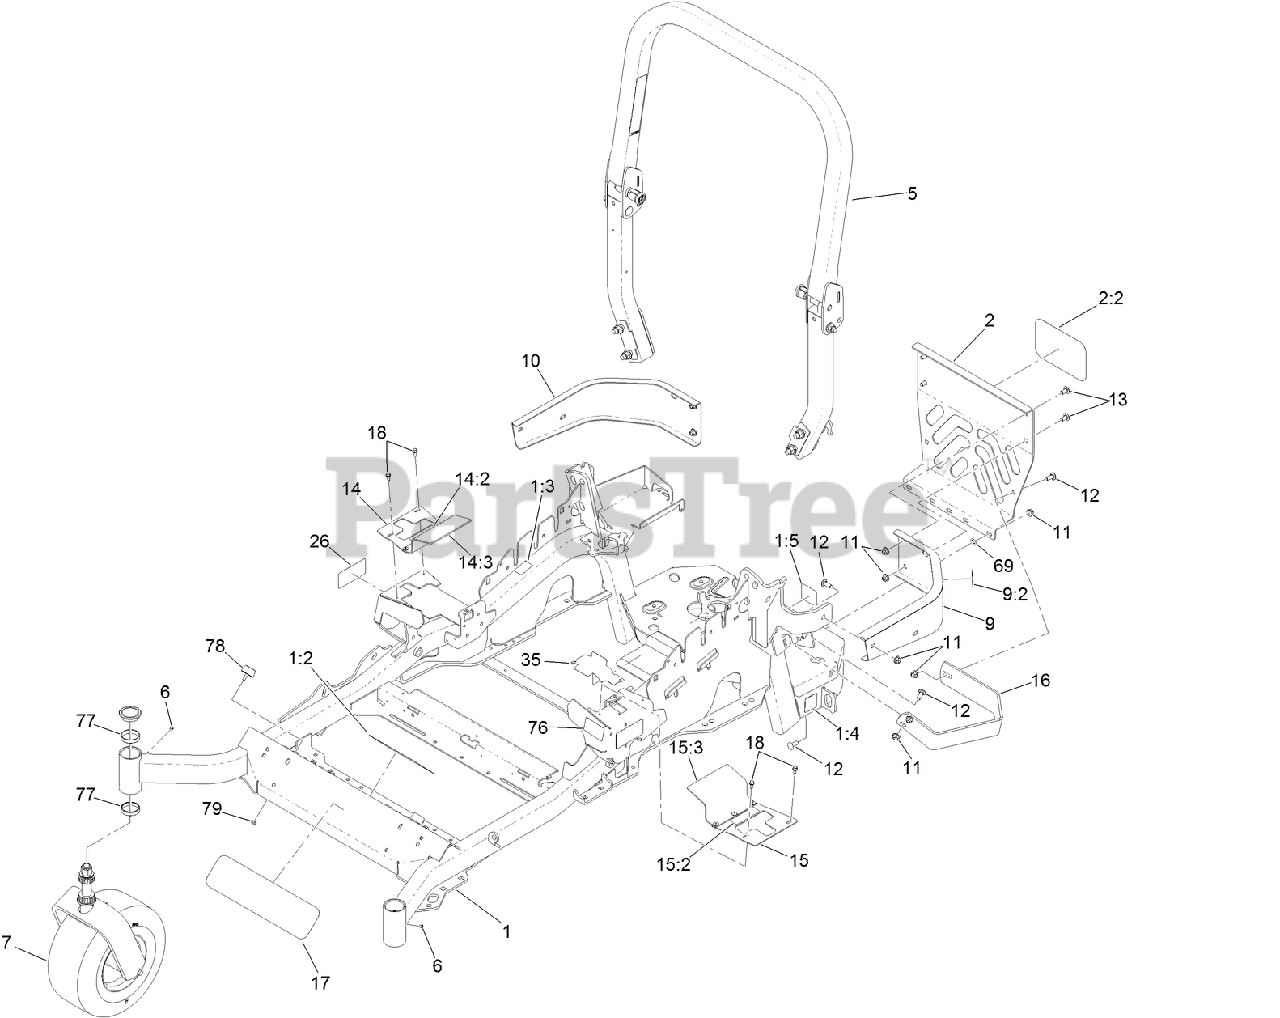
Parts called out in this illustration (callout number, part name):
1	MAINFRAME ASM
1:2	DECAL-DANGER
1:3	DECAL-WARNING
1:4	DECAL-HAZARD, PINCHED FINGER
1:5	DECAL-SPARK ARRESTER
2	REAR GUARD ASM
2:2	DECAL
5	ROPS ASM
7	Caster Wheel ASM
9	LH BUMPER ASM
9:2	DECAL-WARNING
10	BUMPER-RH
11	NUT-HF, NI
12	SCREW-CARR
13	SCREW-CARR
14	RH MOTION CONTROL COVER ASM
14:2	DECAL-CONTROL, MOTION
14:3	FLAP-RUBBER
15	LH MOTION CONTROL COVER ASM
15:2	DECAL-CONTROL, MOTION
15:3	FLAP-RUBBER
16	GUARD-MUFFLER
18	SCREW-HWH
35	GUARD-BELT
69	NUT-PUSH
76	DECAL-FUEL FILL, CE
77	CUP-BEARING
78	BUMPER
79	NUT-HF
